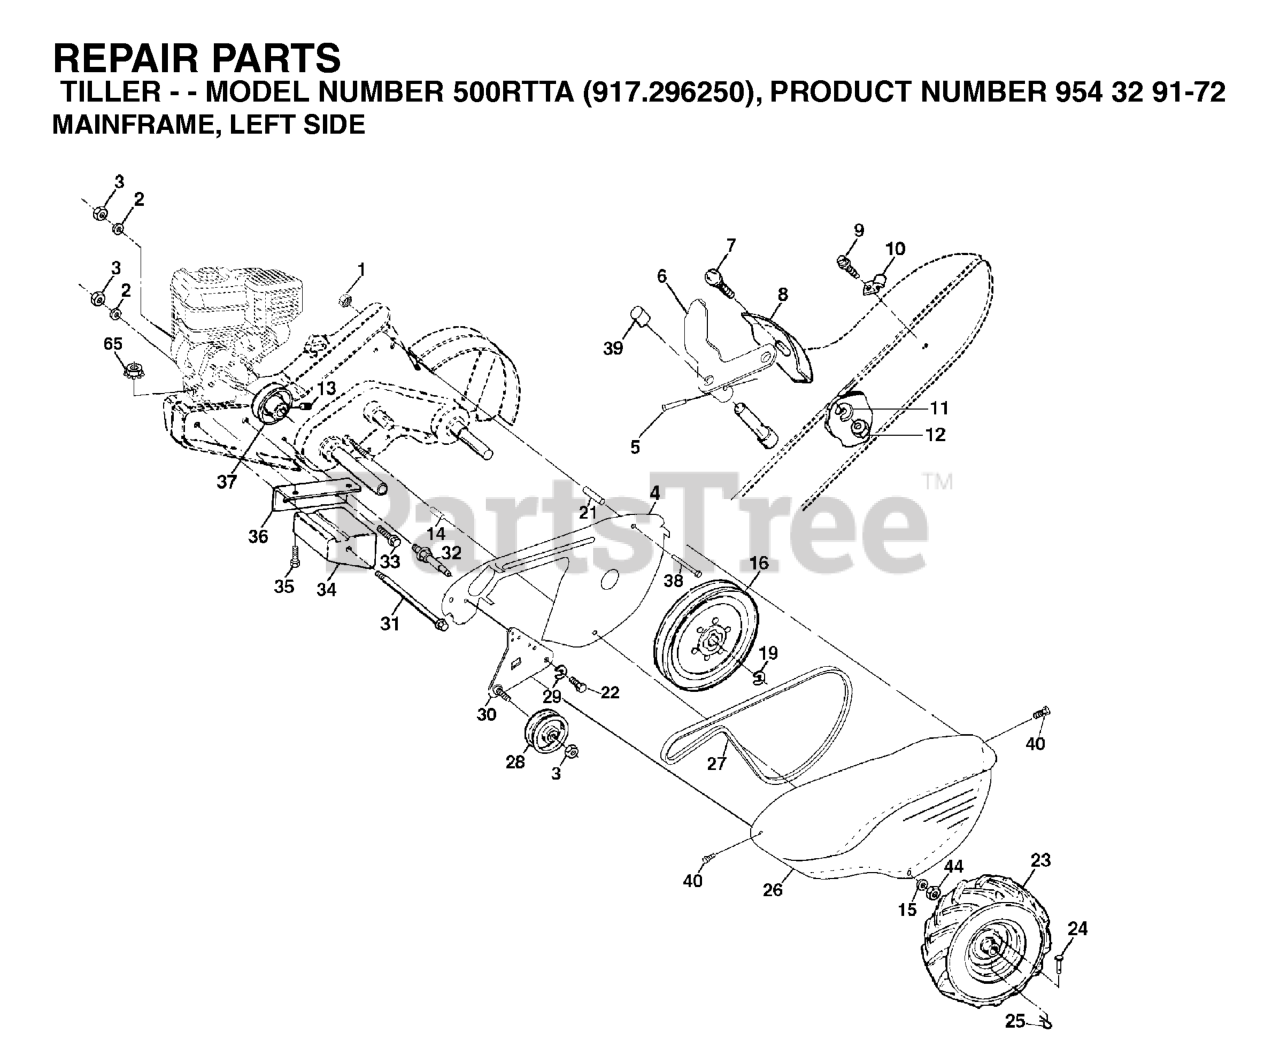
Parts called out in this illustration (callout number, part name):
1	NUT
2	WASHER, LOCK 3/8
3	NUT.HEX.3/8-16UNC
4	SHIELD
5	PIN.SPIROL.FLARED
6	LEVER ASM CRT
8	PANEL.INDICATOR.SHIFT.BLACK
9	TAPPING SCREW
10	CONDUIT.CLIP.PLATED
11	LOCKWASHER
12	NUT
14	SPACER CRT
15	WASHER
16	SHEAVE, TRANSMISSION
19	RETAINING RING LT
21	SPACER-SPLIT.327 X .42
23	TIRE.13X5-6.CHEVRON.TILLER
24	RIVET,DRILLED
25	RETAINER M
26	RP BELT GUARD
27	V-BELT
28	PULLEY-IDLER TI
30	BRACKET.ASM.IDLER.BLACK
31	BOLT.FIN.HEX.3/8-16UNC
32	SHIFT ARM CRT
33	BOLT
34	COUNTERWEIGHT.LH.CRT
35	BOLT
36	BRACKET LH CRT
37	RP.ENGINE PULLEY
38	BOLT
39	CAP.PLUNGER.BLACK
40	SCREW.HEX.WSH.SLT.#10-24X.50
44	NUT.71038.31-18.HEX.NYLOCK
65	LOCKNUT-FLANGE 5/16-18
